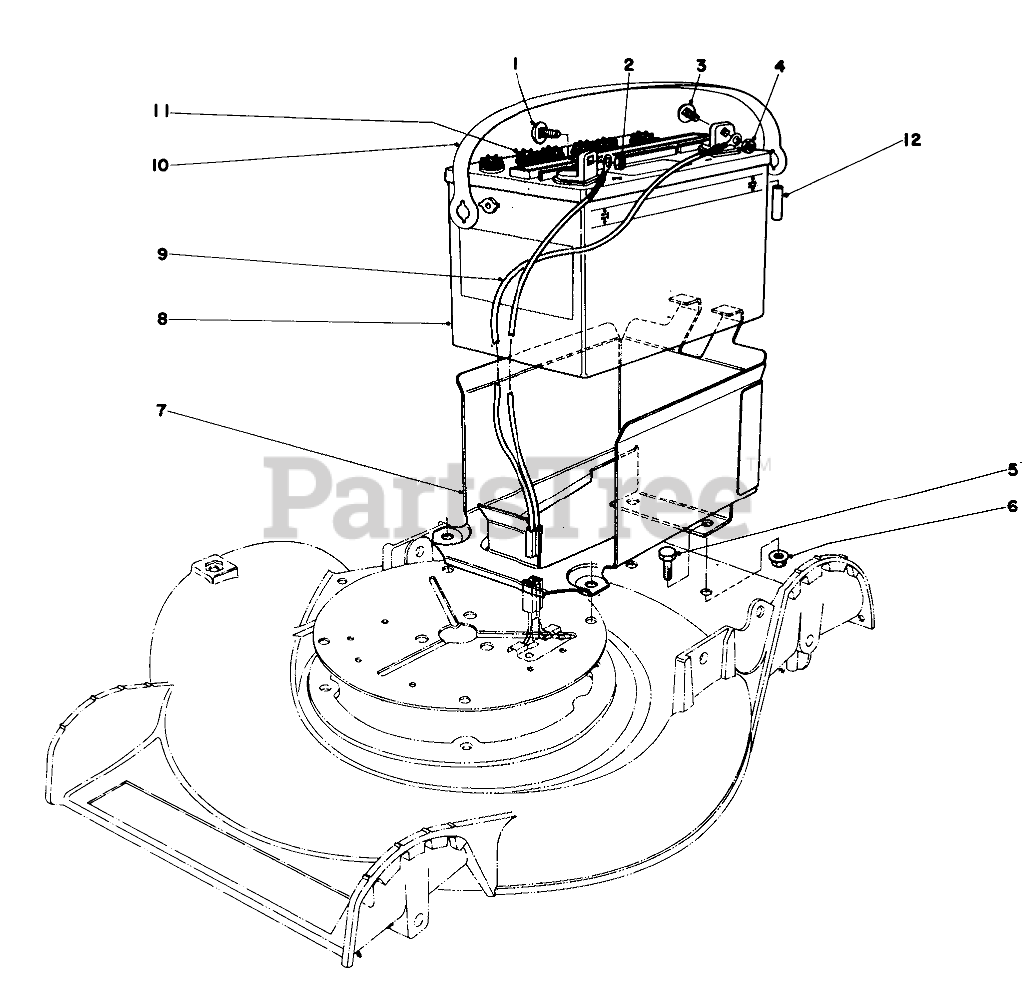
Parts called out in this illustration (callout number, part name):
1	SCREW-CARR
2	Full Nut
3	Bolt-Carriage
4	Full Nut
5	SCREW-HH
6	NUT-HF
7	Bracket-Battery
8	Battery & Electrolyte (Incl. Ref. #9 & 10)
9	Harness Battery
10	Carrying Strap
11	Vent Cap
12	Vent Tube
